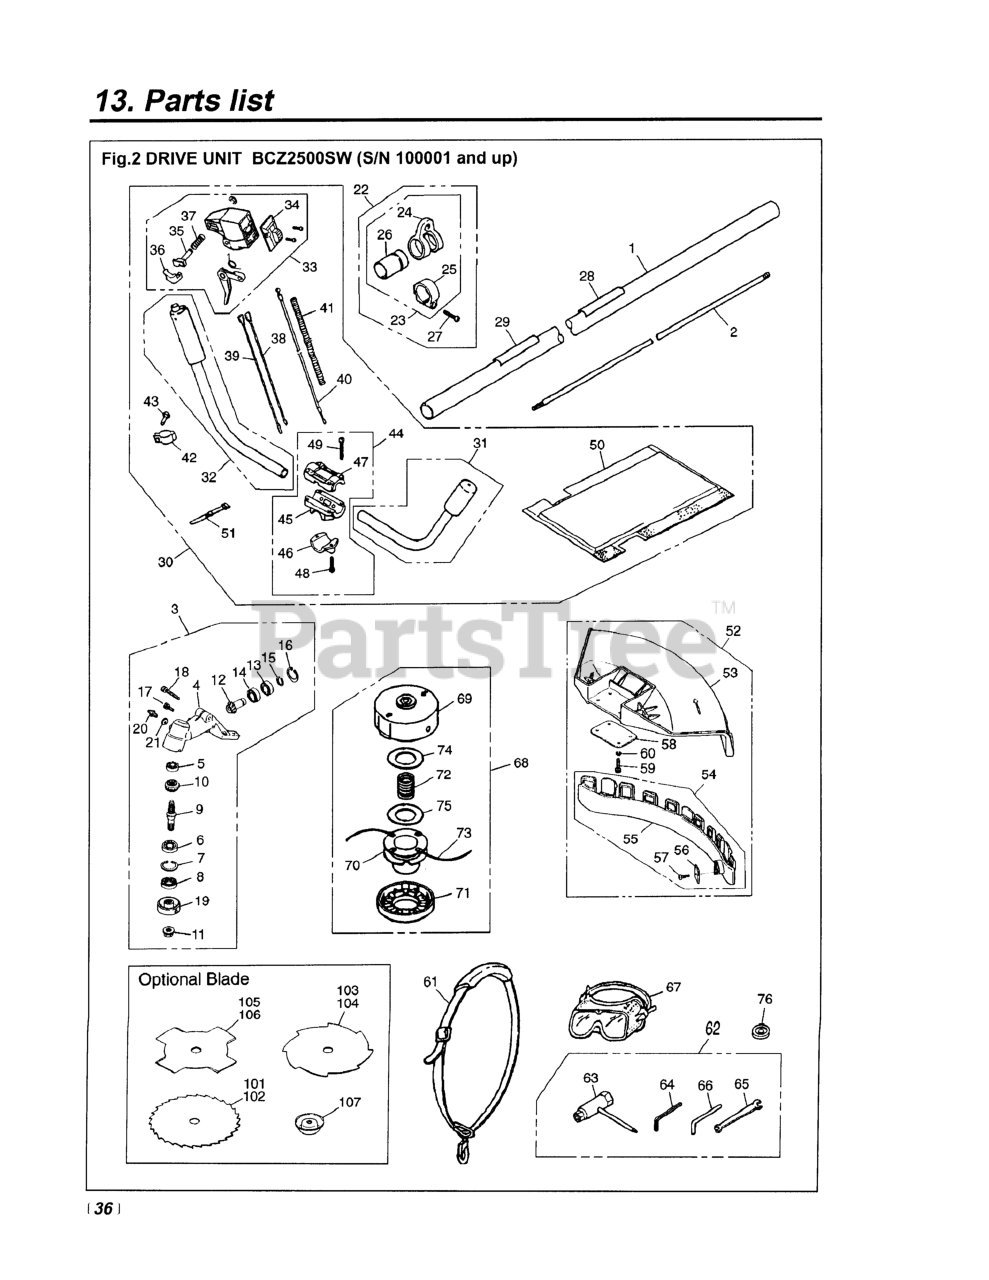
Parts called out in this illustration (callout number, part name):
1	PIPE COMP (REPLACES -12100)
2	SHAFT (RPLS -12212)
3	GEARCASE ASSY (RPLS -13000)
4	GEARCASE
7	RING, SNAP, M26 X 1.2
8	SEAL, OIL
9	SHAFT
10	GEAR
11	NUT
12	PINION
16	RING, SNAP, M24 x 1.2
17	BOLT, M5 X 10
18	BOLT
19	HOLDER (A)
20	FITTING, GREASE
21	WASHER, M6 X .8
22	HANGER ASSEMBLY
23	HANGER COMPLETE
24	HANGER
25	CLAMP
26	SLEEVE
27	SCREW, M5 x 25
28	NAMEPLATE
29	PLATE, CAUTION
30	KIT, BIKE HANDLE (BCX, BCZ)
31	HANDLE, L, COMP
32	HANDLE, R, COMP
33	LEVER ASSEMBLY
38	CORD (A), BLACK
39	CORD (B), RED
40	CABLE COMPLETE
41	TUBE
42	CLAMP
43	SCREW, M5 X 16
44	BRACKET ASSY (REPLACES -14100)
46	CAP, LOWER
47	CAP, UPPER (RPLS -14191)
48	BOLT, M5 X 22
49	BOLT, M5 X 25
50	PROTECTOR
51	BAND
52	GUARD ASSEMBLY
53	GUARD
54	PLATE COMPLETE
55	PLATE
56	BLADE
58	PLATE
59	BOLT, M5 X 16
60	WASHER, SPRING M4 x 1.3
61	STRAP ASSY.
63	SOCKET
64	WRENCH (TOOL)
65	SPANNER, 8 X 10 (RPLS 2540- )
66	BAR
67	GOGGLE
68	4
69	CASE (RPLS -15112)
70	HOLDER, CORD (RPLS -15141)
71	COVER (RPLS -15130)
72	SPRING (RPLS -99161)
73	CORD
74	PLATE, LARGE
75	PLATE, SMALL
76	HOLDER (B)
101	BLADE, 9
102	BLADE, 9
103	BLADE, 8
104	BLADE, 9
105	BLADE, 8
106	BLADE, 9
107	COVER
